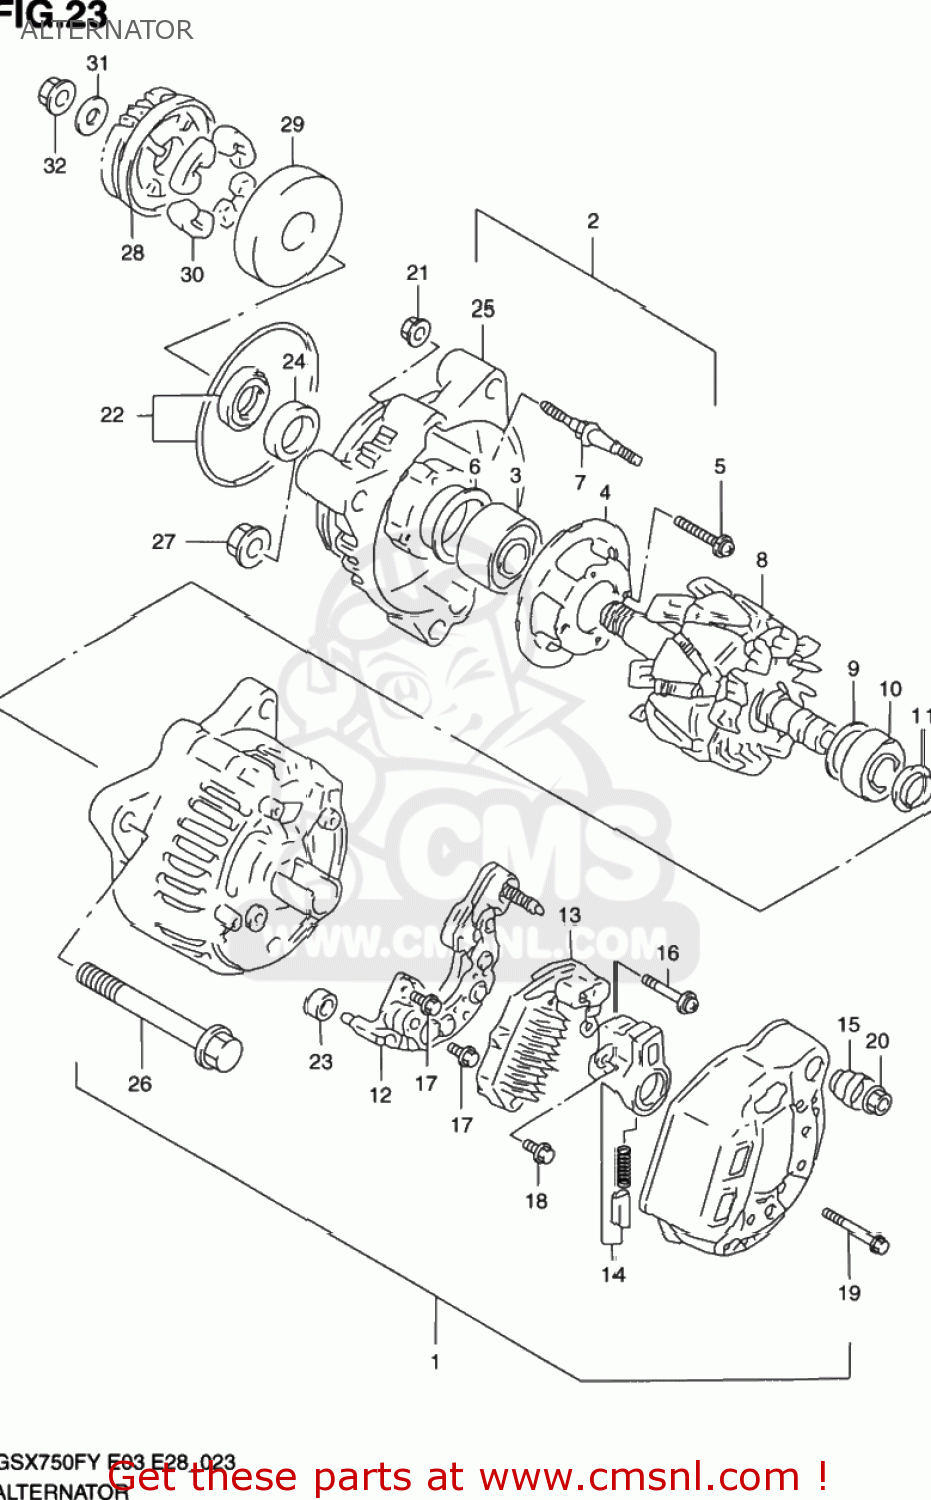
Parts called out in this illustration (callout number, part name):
1	ALTERNATOR ASSEMBLY
2	FRAME,DRIVE END
3	BEARING
4	RETAINER
5	SCREW(4X14)
6	COVER,BEARING
7	STUD BOLT
8	ROTOR ASSY
9	COVER,BEARING
10	BEARING
11	COVER(2)
12	HOLDER,RECTIFIER
13	REGULATOR ASSY
14	HOLDER,BRUSH
15	INSULATOR,TERMINAL
16	SCREW
17	SCREW 4X6
18	SCREW
19	SCREW
20	NUT
21	NUT
22	SERVICE KIT(A)
23	SERVICE KIT,B
24	SPACER
25	FRAME,END
26	BOLT
27	NUT
28	GEAR,GENERATOR DRIVEN
29	HOUSING,GENERATOR GEAR DAMPER
30	DAMPER,GENERATOR DRIVEN
31	WASHER
32	NUT
